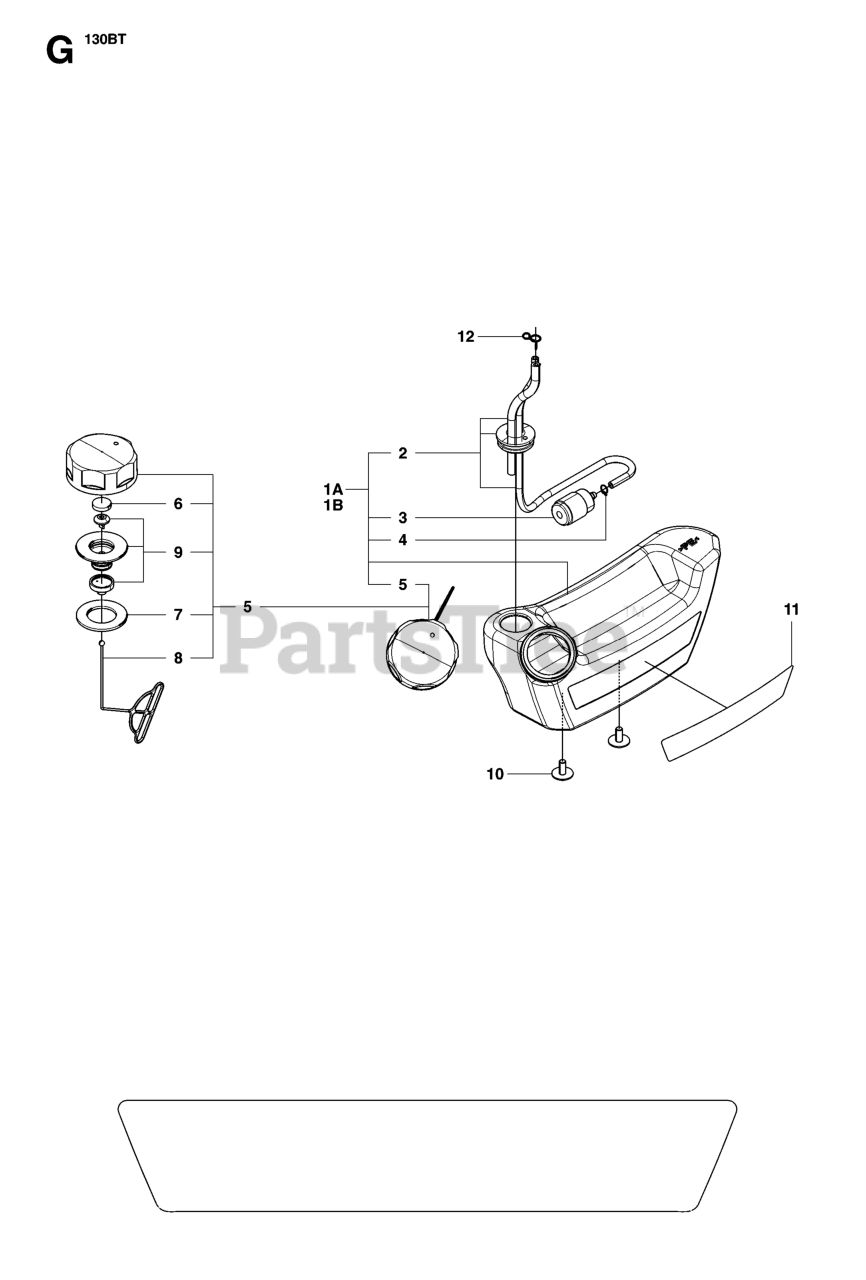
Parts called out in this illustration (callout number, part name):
1B	TANK ASSY
2	PIPE C
3	FILTER
4	CLIP
5	ASSY FUEL CAP
6	FILTER
7	PACKING
9	HOLDER-A
11	LABEL TANK
12	CLIP
